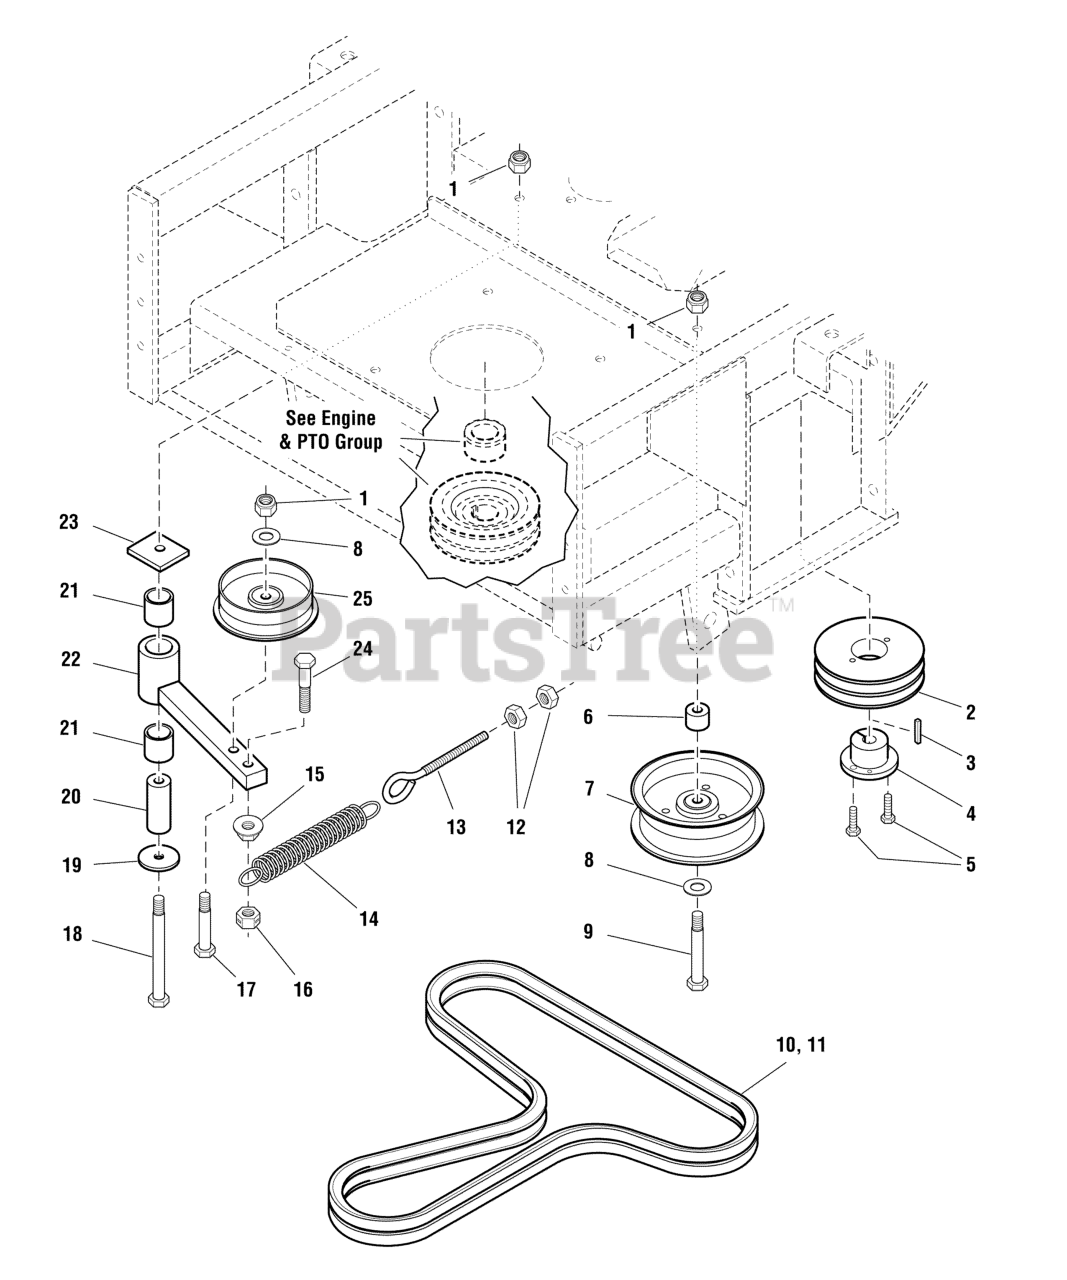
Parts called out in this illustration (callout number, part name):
1	NUT, 3/8-16 HEX NYLON LOCK
2	PULLEY, Pump Drive
3	KEY, 5MM SQ. x 25MM w/ Round Ends
4	BUSHING, Tapered Hub
5	BOLT, 1/4-20 X 1" GD5 CZ
6	SPACER, .39 x 1.00 x .79
7	PULLEY, Idler
8	WASHER, 3/8 SAE
9	BOLT, 3/8-16 X 2-3/4" GD5 CZ
10	BELT, Pump Drive (set of 2)
11	BELT, Pump Drive, Liquid Cooled Model (Set)
12	NUT, 3/8-16 Hex
13	EYE BOLT, 3/8-16 X 5, 2.88THRD, 1EYE, CZ
13	EYEBOLT, 3/8-16 x 6"
14	SPRING, Extension, Swivel End
15	NUT, 3/8-16 Hex Serrated Flange
16	NUT, 3/8-16 Hex Side Lock
17	BOLT, 3/8-16 X 2-1/4" GD5 CZ
18	BOLT, 3/8-16 X 4" GD5 CZ
19	WASHER, 3/8 x 1-3/4
20	SPACER, .39 X 1.00 X 2.55, SS
21	BUSHING, Brass
22	WELD, ARM, PUMP DRIVE IDLER - BLK
23	SPACER, Idler Pivot
24	BOLT, 3/8-16 X 1-3/4" GD5 CZ
25	PULLEY, Idler (Single Flange)
